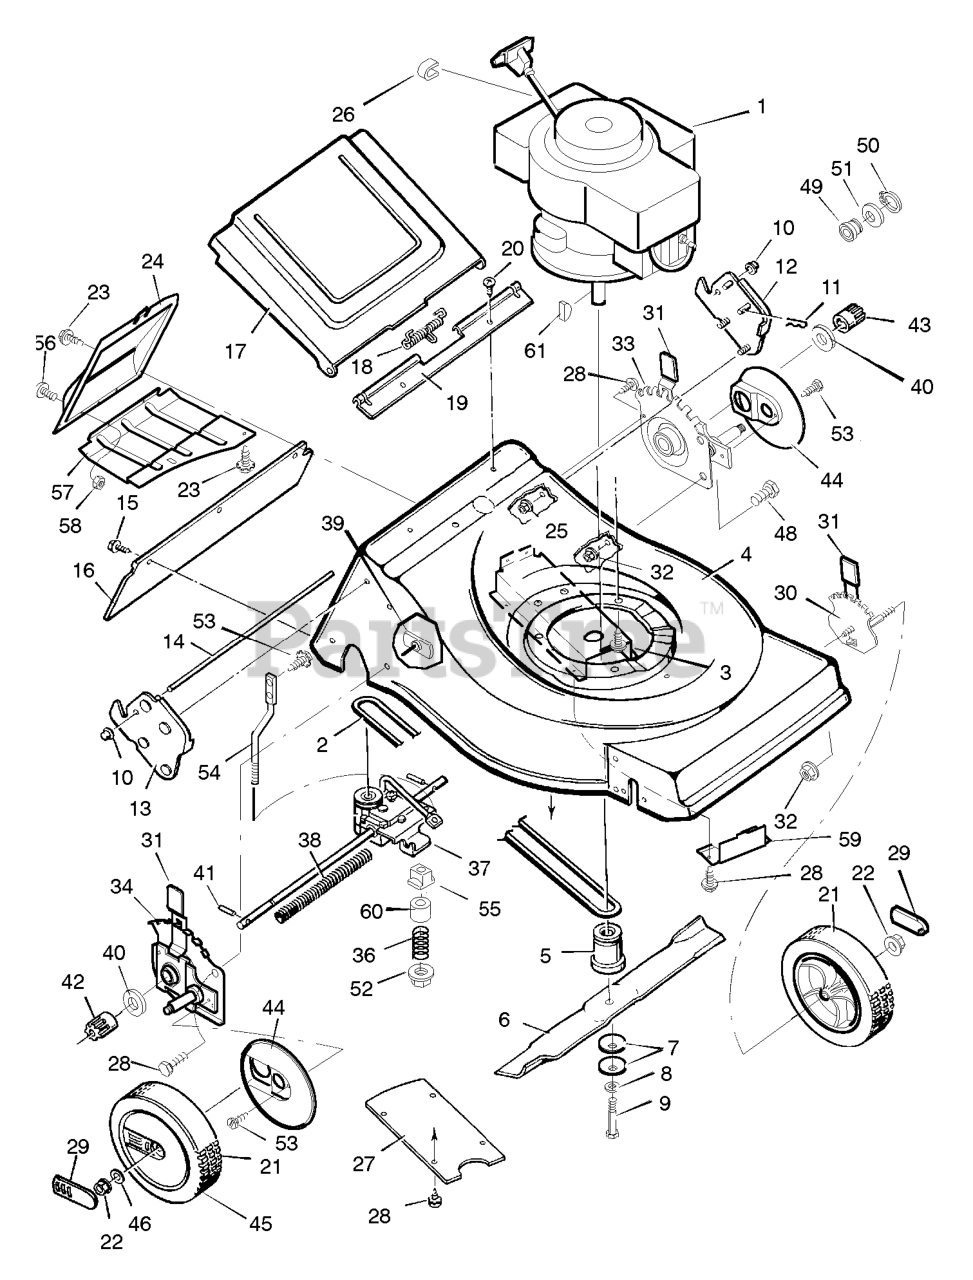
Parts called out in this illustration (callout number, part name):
1	Engine *
2	Belt, Drive
3	Bolt, Engine
4	Housing
5	Adapter, Blade
7	Washer, Belleville
10	Push On Cap
11	Pin, Hair
12	Handle Bracket, Left
13	Handle Bracket, Right
14	Rod, Door Pivot
16	Deflector, Rear
17	Door, Rear
18	Spring, Torsion
19	Spacer, Door
21	WHEEL & TIRE ASSEMBLY, White, 8"
22	Nut
24	Transmission, Cover
25	Nut, Flange
26	Stop, Rope
27	Cover, Belt
29	Hub Cap, Front
30	Height Adjuster, Front
32	Nut, Flange
33	Height Adjuster, Left Rear
34	Height Adjuster, Right Rear
36	Spring, Extension
37	Transmission TIM .50
38	Shield, Axle
39	Nut, Special
40	Washer, Thrust
41	Pin, Drive
42	Pinion, Right
43	Pinion, Left
44	Cover, Dust
45	Wheel, Drive - White
46	Washer, Thrust
48	Bolt
49	Bearing and Retainer
50	Ring, Retaining
52	Locknut
54	Support, Spring
55	Bushing
56	Screw
57	Cover, Lower
59	Cover, Front Belt
61	Key, Woodruff
